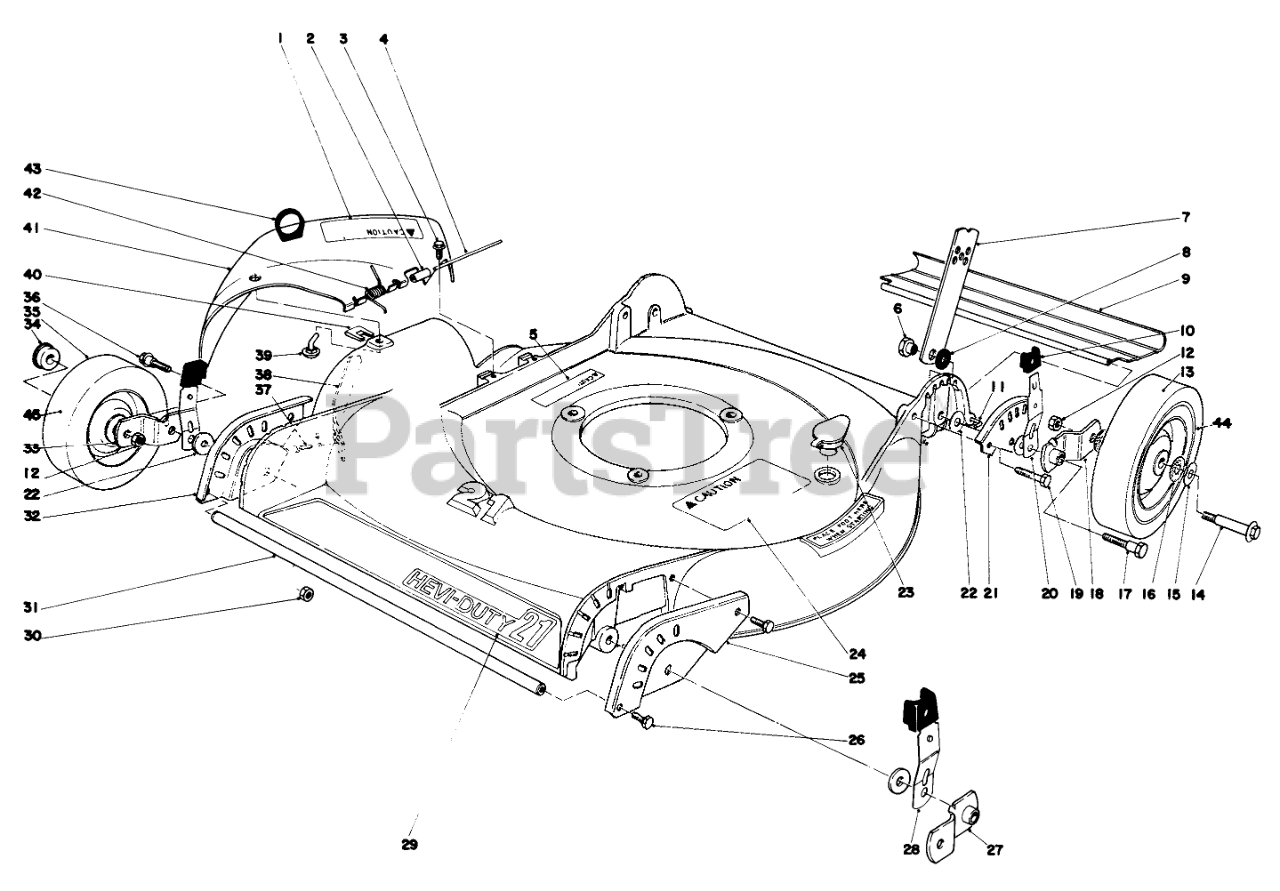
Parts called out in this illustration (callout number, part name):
1	Caution Decal
2	SLEEVE
3	SCREW
4	HINGE PIN
5	Decal
6	HANDLE PIVOT NUT
7	HANDLE LATCH
8	HANDLE LATCH SPACER
9	SHIELD - TRAILING
10	KNOB-ARM
11	SHIELD ROD
12	Nut
13	Wheel Assembly (Incl. Ref. #34 & 44)
15	SPRING WASHER
16	FELT WASHER
17	PIVOT SCREW
18	PIVOT ARM ASM "B"
19	SCREW-HH
20	Spring Arm Rear
21	Wheel Quadrant L.H.
22	WASHER-PIVOT
23	WASHOUT PLUG
24	DECAL SAF INST
25	LH WHEEL QUAD FR
26	SELF TAPPING SCREW
27	Pivot Arm "C"
28	Spring Arm Assembly (Front)
29	Decal Hevi-Duty 21
30	Nut
31	Bumper
32	RH WHEEL QUAD FRONT
33	Pivot Arm Assembly "D"
34	BEARING-BALL
35	Wheel Assembly (Incl. Ref. #34 & 45)
36	PIVOT SCREW
37	SCREW THD 1/4 20 5/8
38	Bar Safety
39	BAG CHUTE PIN
40	BAG CHUTE CLIP PIN
41	Deflector
42	TORSION SPRING
43	LIFT LOOP
45	TIRE 7"
